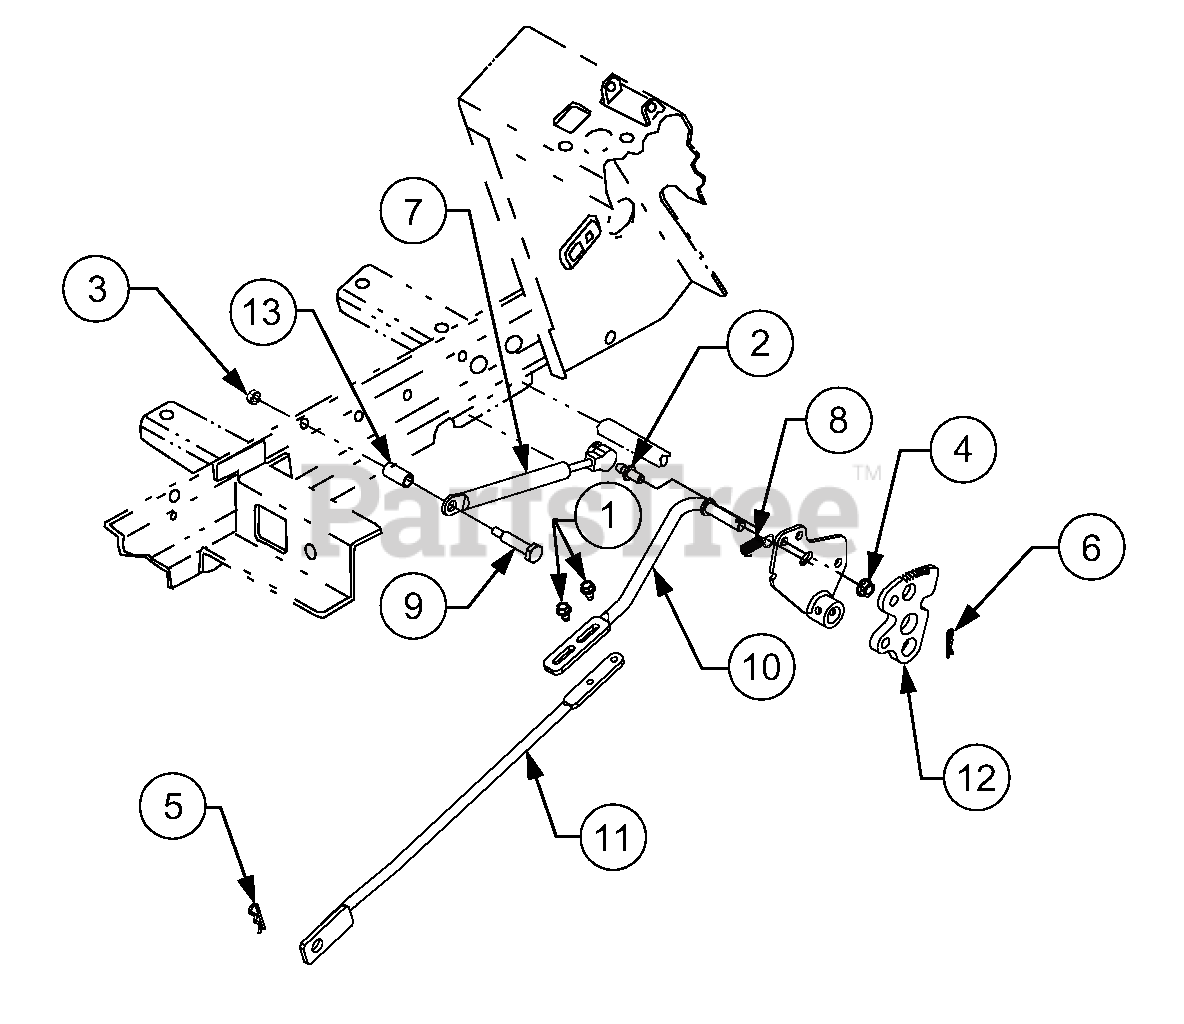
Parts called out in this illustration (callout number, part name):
1	Screw, Hex Wsh Hd Tapp, 1/4-20 x .75
2	Screw, Ball, 5/16-18 x.56
3	Nut, Hex Sems, 1/4-20
4	Nut, Hex Flange Lock, 1/4-20
5	Pin, Internal Cotter
6	Pin, Internal Cotter
7	Cylinder, Damper
8	Spring, Extension, 3/8 OD x 1.44
9	Bolt, Shoulder, .374 Dia x 1.375
10	Rod, Front Control
11	Rod, Rear Hydro Control
12	Plate, Cruise
13	Spacer, Split Tubing, .375 ID x 1.04
